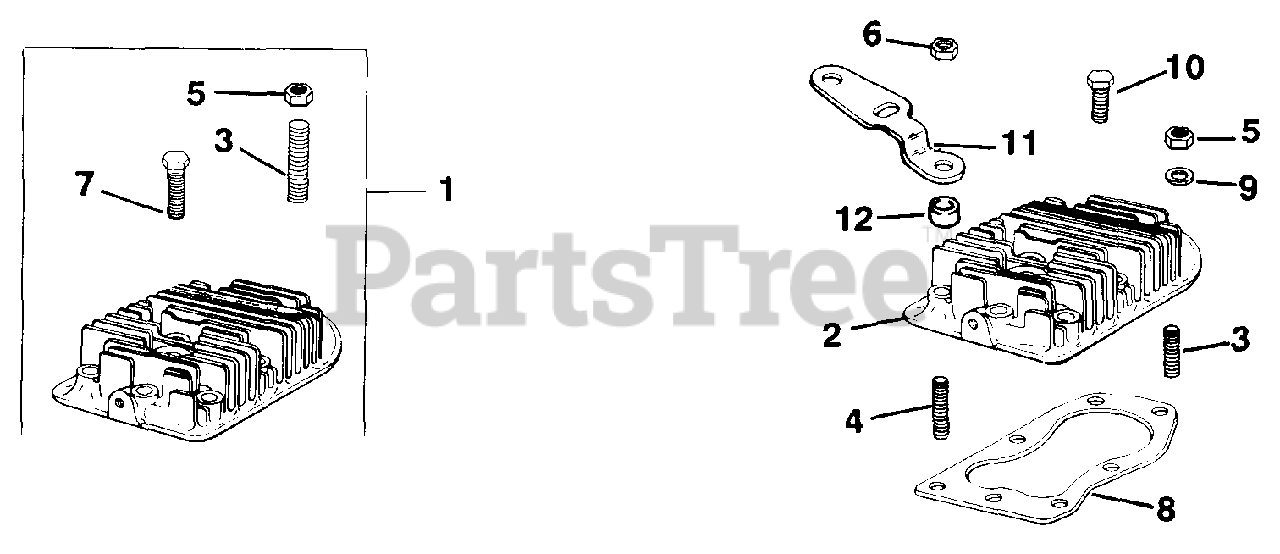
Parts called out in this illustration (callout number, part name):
1	KIT, CYLINDER HEAD
5	NUT, 5/16-18 GRADE 5 USE 25 100 22-S
7	SCREW, SEMS 1/4-20X5/8" USE 25 086 539-S
9	WASHER, FLAT 5/16"
